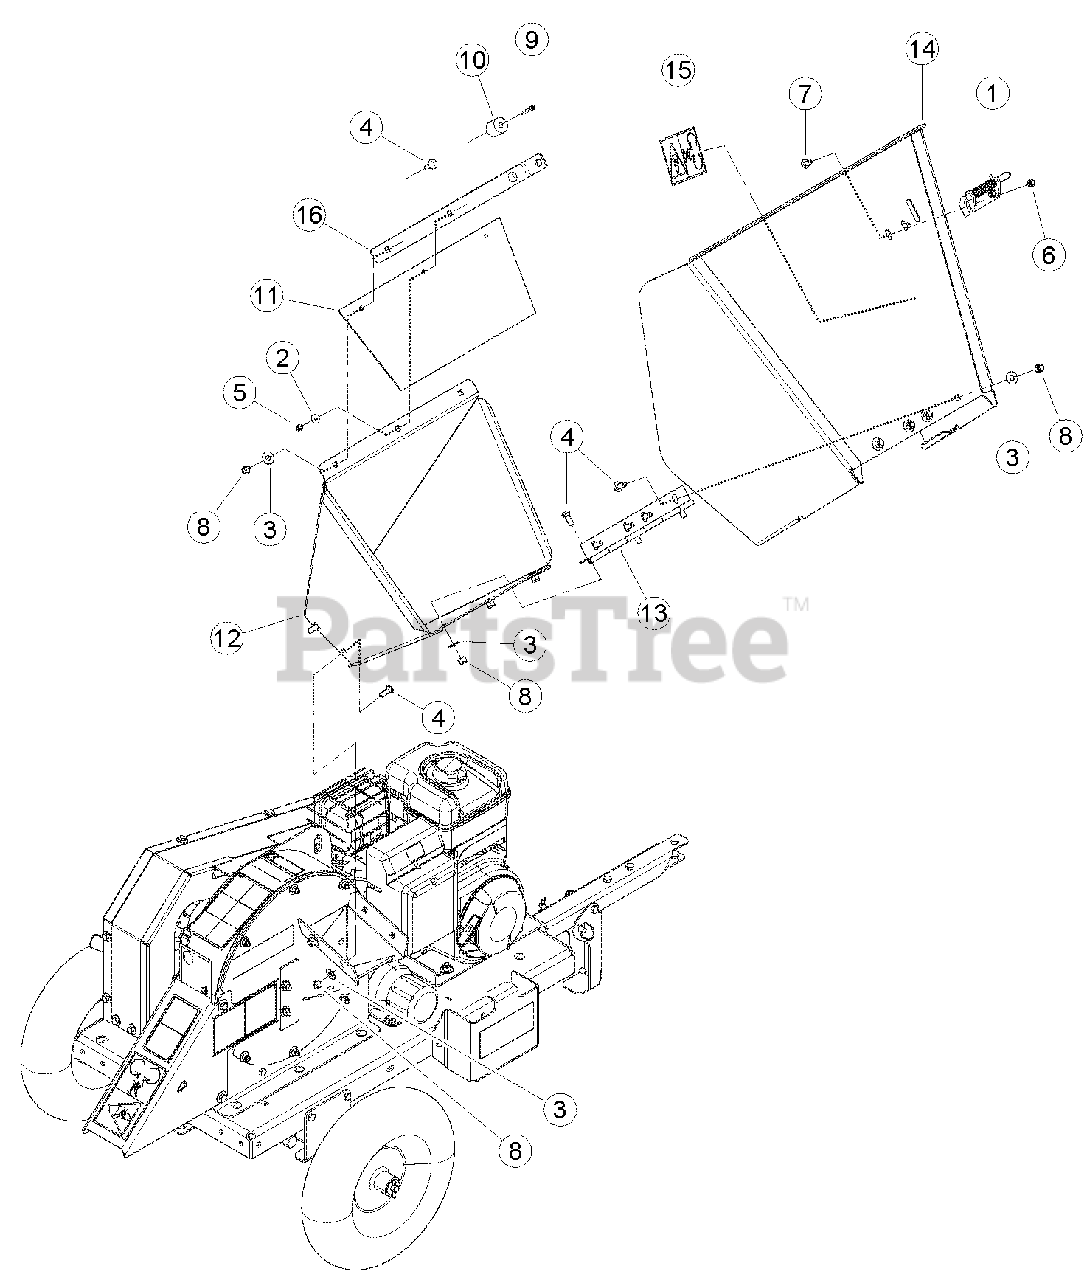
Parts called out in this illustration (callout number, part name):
1	LATCH, RH HINGE
2	WASHER, 1/4 FLAT ZP
3	WASHER, 3/8 FLAT ZP
4	BOLT, 3/8 X 1 CRG GR5 NC ZP
5	NUT, 1/4 NE NYLOCK ZP
6	NUT, 5/16 NE NYLOCK ZP
7	BOLT, 5/16 X 3/4 CRG GR5 NC ZP
8	NUT, 3/8 NE NYLOCK ZP
9	SCREW, 1/4 X 1-1/2 SKT HD CAP
10	BUMPER, RECESSED RUBBER
11	FLAP, CHIPPER CHUTE
12	WELDMENT, HOPPER
13	HINGE, CHUTE EXTENSION
14	ASSEMBLY, 4-1/2" EXTENSION TRAY, SERVICE PART
15	DECAL, BLADE DANGER ISO
16	STRIP, FLAP RETAINER
